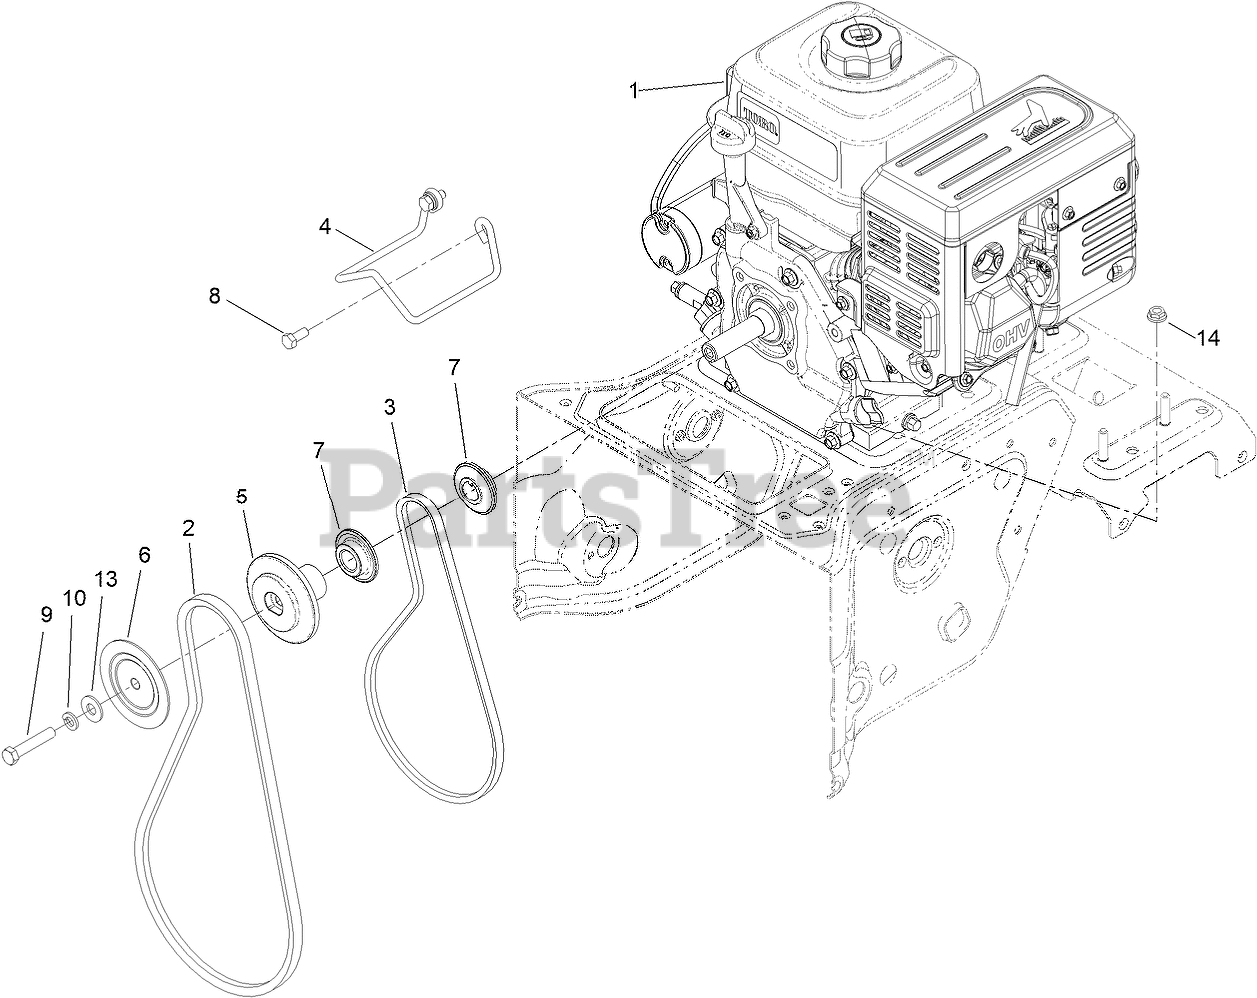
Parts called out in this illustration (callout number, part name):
1	ENGINE-G210FDS-1
2	BELT-V
3	BELT-V
4	GUIDE-BELT
5	PULLEY-AUGER, REAR
6	PULLEY-AUGER, FRONT
7	PULLEY-ENGINE, TRACTION
8	SCREW-HH
9	SCREW-HH
10	WASHER-LOCK
13	WASHER-PLAIN
14	NUT-HF
